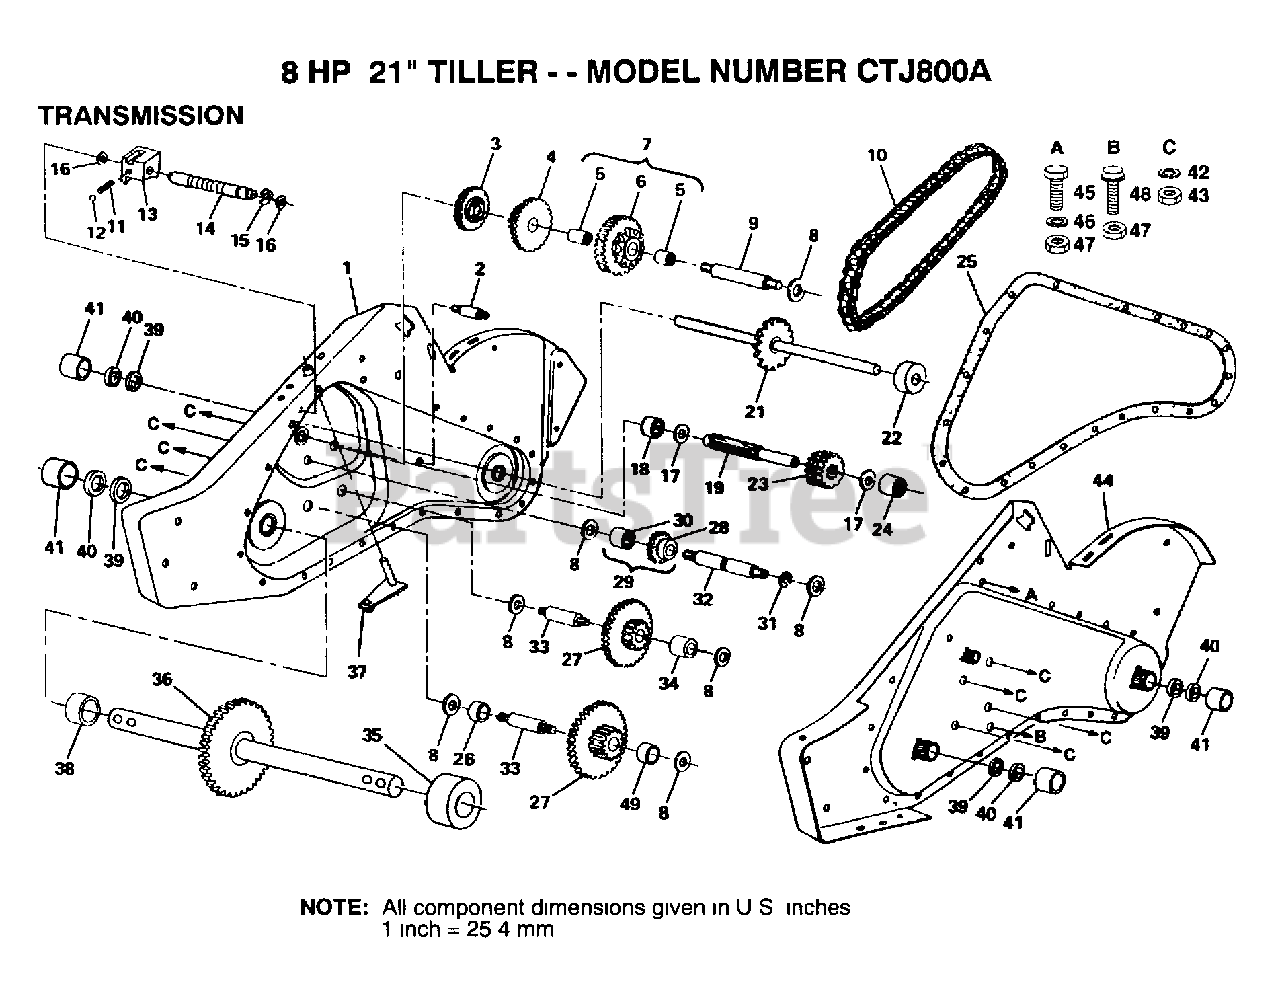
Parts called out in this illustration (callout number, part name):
2	BOLT TI
3	REVERSE GEAR TI
4	CLUSTER GEAR TI
5	"CRT, BEARING"
7	SPROCKET ASSY TI
8	WASHER
9	REDUCTION SHFT TI
10	CHAIN TI
11	SPRING-SHIFT CRT
13	SHIFT FORK TI
14	SHIFT SHAFT TI
15	KLIP RING
17	"T, BEARING"
18	"TI, BEARING"
19	SHAFT INPUT T
21	SHAFT TINE CRT
22	SPACER CRT
23	INPUT PINION TI
24	NEEDLE BRNG LT
25	GEARCASE GSKT TI
26	SPACER CRT
27	GEAR CLUSTER CRT
28	REVERSE GEAR TI
29	GEAR ASSY TI
30	NEEDLE BEARING TI
31	KLIP RING
32	REVERSE SHAFT TI
33	SHAFT CRT
34	SPACER CRT
35	SPACER CRT
36	SHAFT ASSY CRT
38	SPACER CRT
41	CUP.FORMED.
42	LOCKWASHER
43	NUT.ASF.HEX.7/16
45	BOLT
46	LOCKWASHER
47	NUT.HEX.5/16-18
48	BOLT TI
49	SPACER CRT
